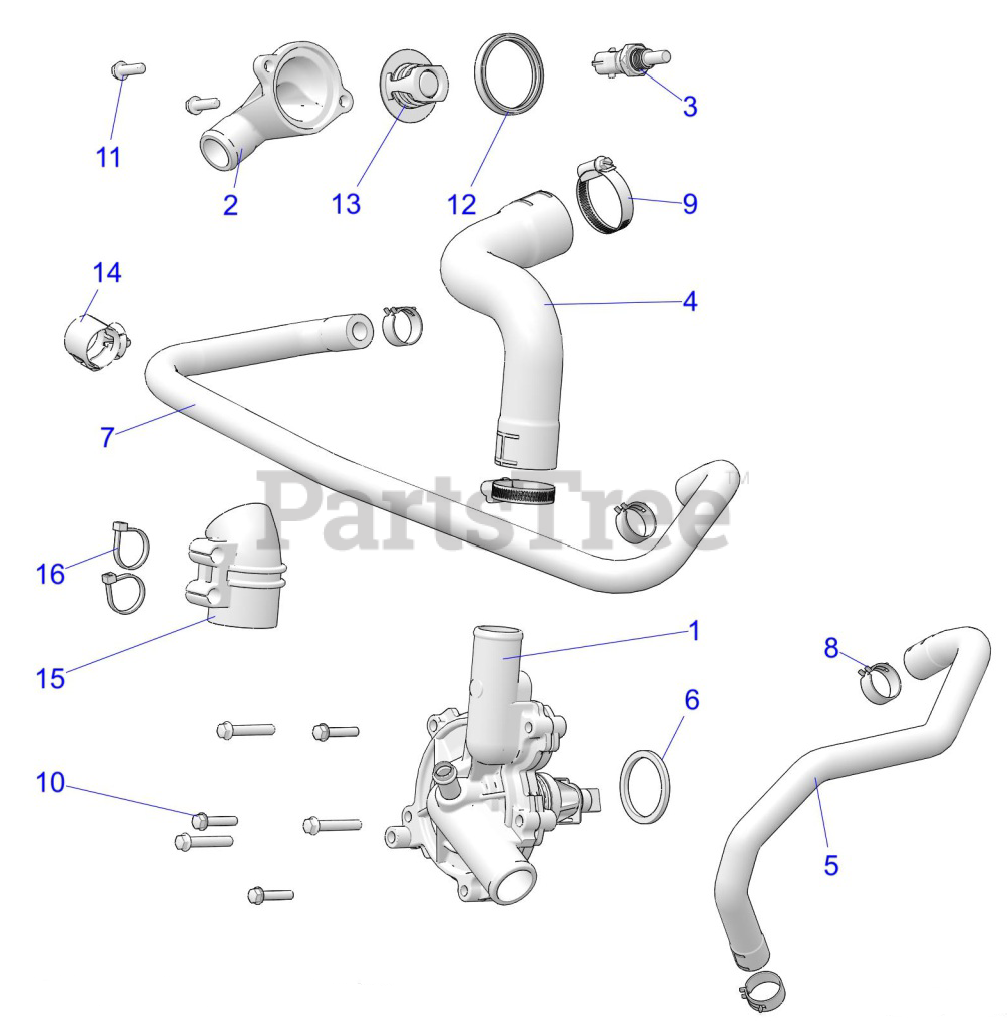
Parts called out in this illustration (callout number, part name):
1	ASM-WATER PUMP
2	COVER-THERMOSTAT
3	SENSOR-THERMISTER
4	HOSE-WATERPUMP-OUT
5	HOSE-OIL COOLER OUT
6	FILTER-WP
7	HOSE-BYPASS LINE
8	CLAMP- HOSE- SPRING
9	CLAMP-HOSE(WORM DR)25-40MM
10	SCR-HXFL-M6X1.0X35-W/PATCHLOK
11	SCR-M6X20-HXFLG-0600214
12	SEAL-THERMOSTAT
13	THERMOSTAT-44M FLANGE-180F
14	CLIP-HOSE
15	SUPPORT-STATOR WIRE
16	CABLE TIE (10)
